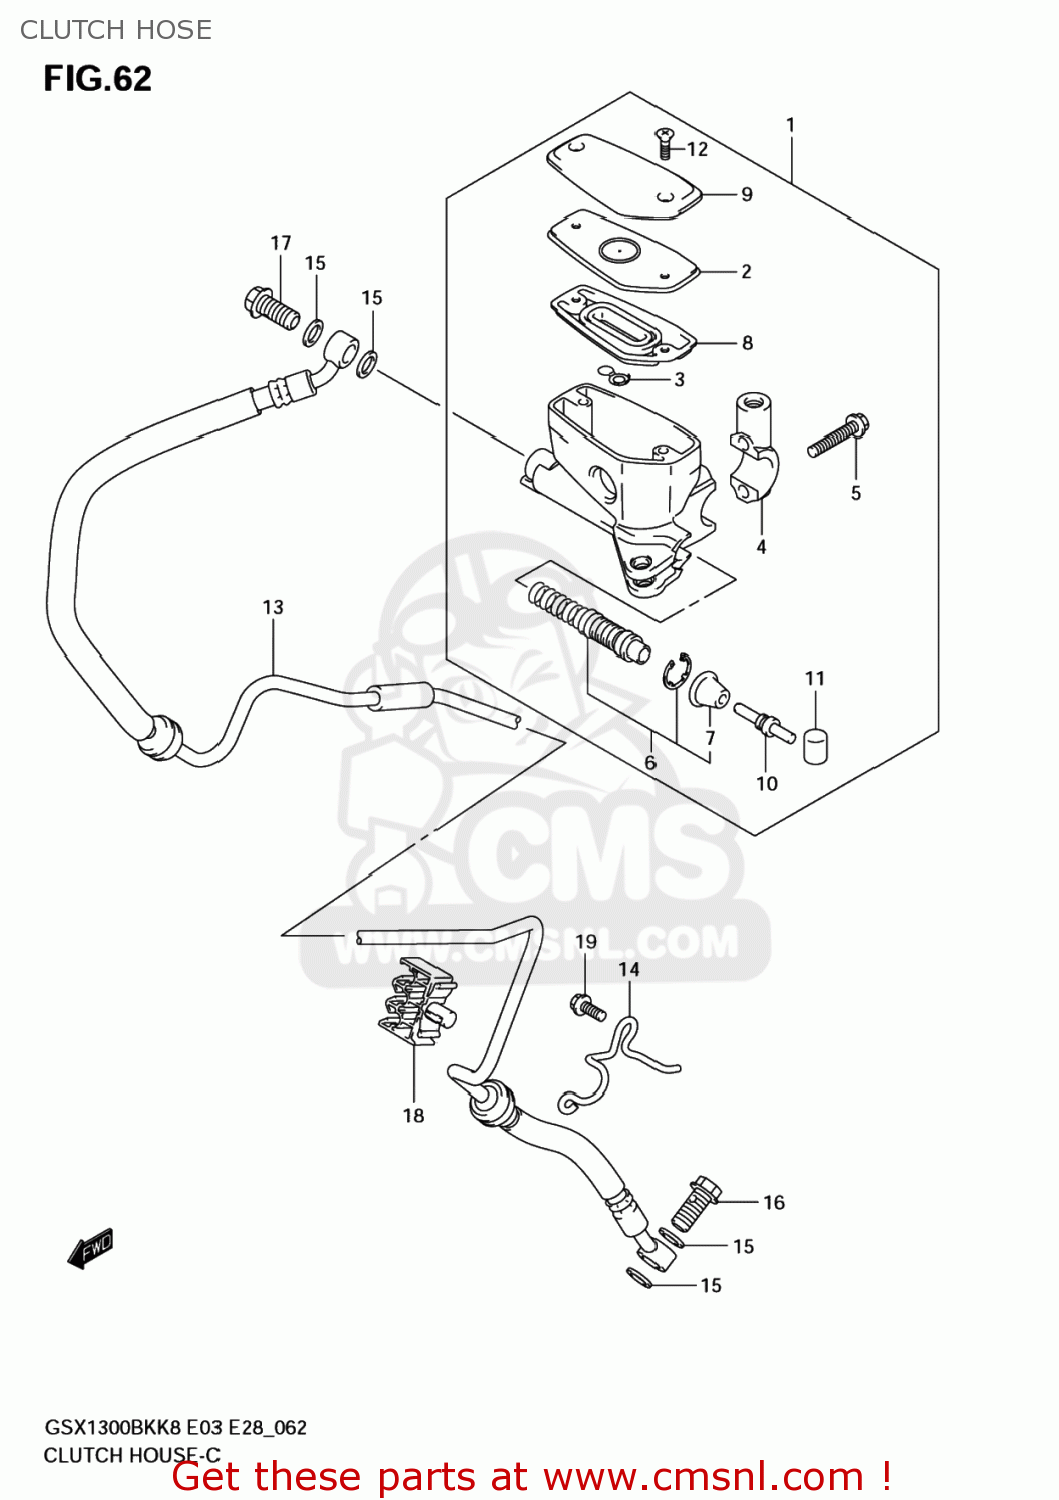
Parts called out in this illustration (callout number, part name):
1	CYLINDER ASSY,CLUTCH MASTER
2	PLATE
3	PROTECTOR
4	HOLDER
5	BOLT(6X22)
6	PISTON & CUP SET
7	BOOT
8	DIAPHRAGM
9	CAP
10	ROD,PUSH
11	BUSH
12	SCREW
13	HOSE,CLUTCH
14	CLAMP,CLUTCH HOSE
15	WASHER(10X15X1.5)
16	BOLT UNION
17	BOLT UNION
18	CLAMP
19	BOLT
